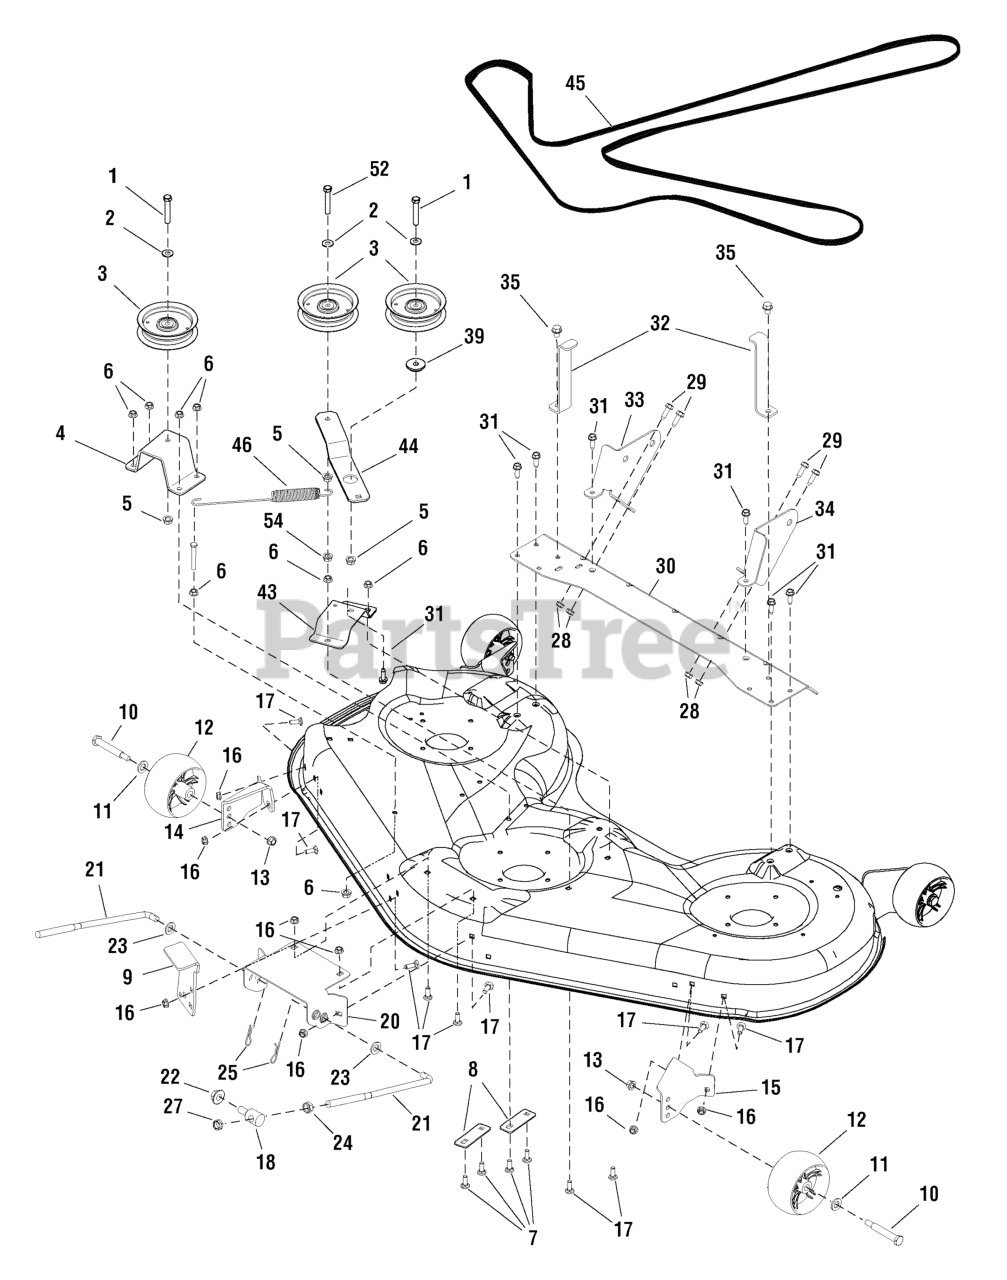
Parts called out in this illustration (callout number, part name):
1	CAPSCREW, Hex Head, 3/8-16 x 2-1/4
2	WASHER, 3/8
3	PULLEY, Idler
4	BRACKET, Fixed Idler, Rear
5	NUT, Hex Flange, 3/8-16
6	NUT, Hex Flange, 5/16-18
7	BOLT, Carriage, Short Neck, 5/16-18 x 1
8	PLATE, Backing
9	UPSTOP, Front, 52" Mower
10	BOLT, Shoulder, 3/8-16 x 3-7/8
11	WASHER 1/2
12	WHEEL, Gauge, 5"
13	NUT, Hex Flange, 3/8-16 ESNA
14	BRACKET, Gauge Wheel, Left
15	BRACKET, Gauge Wheel, Right
16	NUT, Hex Flange, 5/16-18
17	BOLT, Carriage, 5/16-18 x 7/8
18	TRUNNION, Unthreaded
20	HITCH, Front
21	ROD, Front Rail
22	NUT, Hex Flange, Two-Way Lock, 1/2-13
23	WASHER 1/2
24	NUT, Hex Jam, 1/2-13
25	CLIP, Hairpin
28	NUT, Hex Flange 5/16-18 ESNA
29	CAPSCREW, Whizlock 5/16-18 x 3/4
30	SUPPORT, Rear Cross
31	SCREW, Hex Washer Head, Taptit, 5/16-18 x 1
32	UPSTOP, Rear, 46" + 52" MOWERS
33	BRACKET, Rear mower Pickup, Right
34	BRACKET, Rear mower Pickup, Left
35	SCREW, 3/8-16 x 1/2
39	SPACER, 3/8
43	BRACKET, Idler Mount, Front
44	ARM, Idler
45	V-BELT, HA 132"
46	SPRING, Extension, PTO
52	CAPSCREW, Hex Head, 3/8-16 x 2-1/2
54	NUT, Hex Flange, 3/8-16
